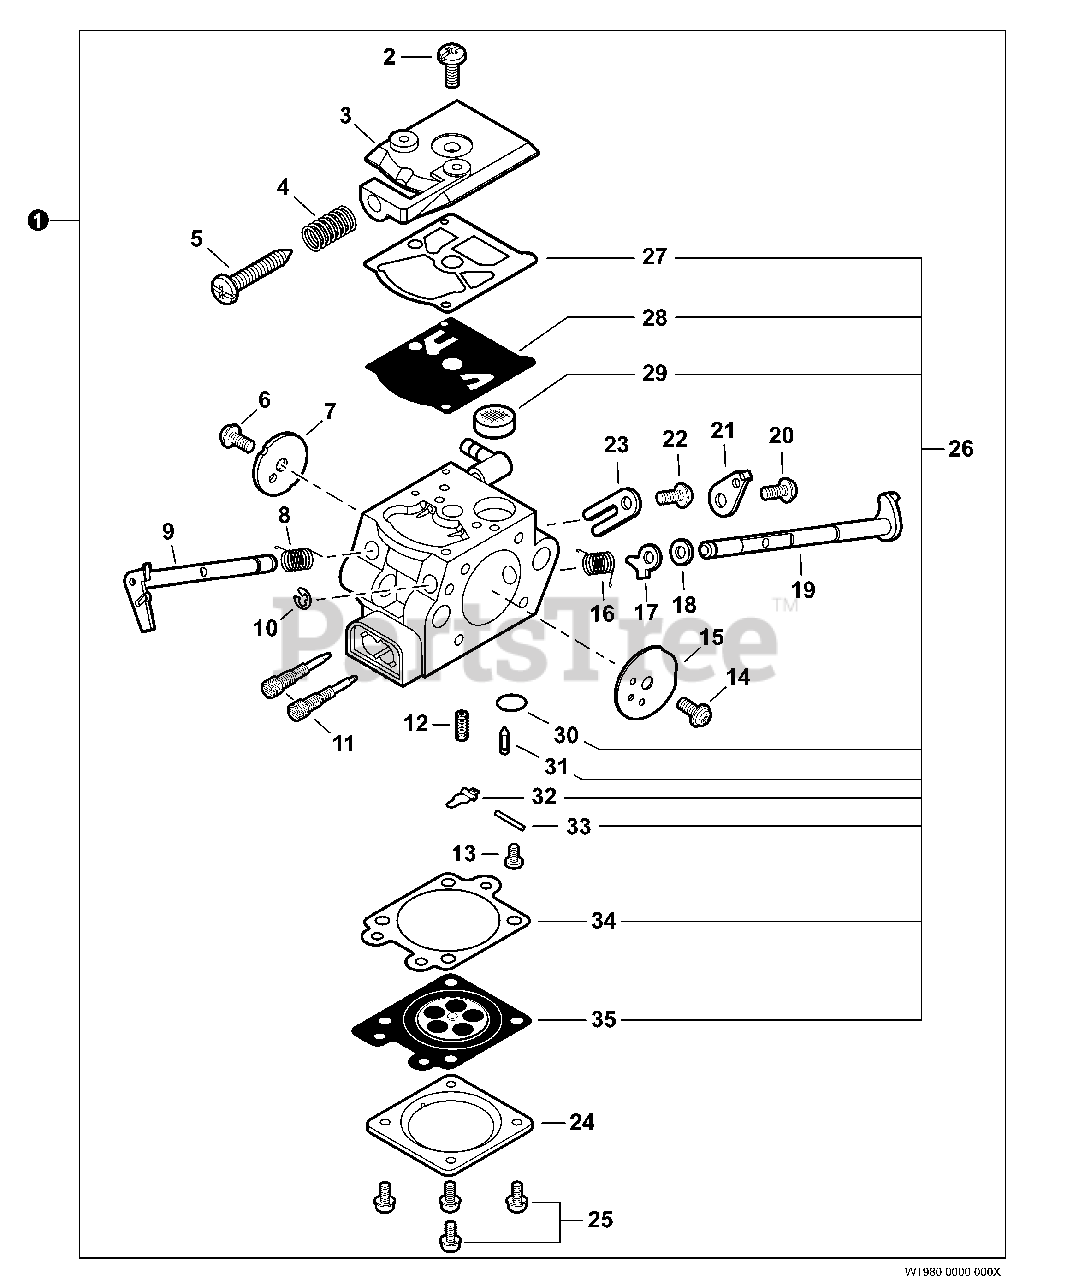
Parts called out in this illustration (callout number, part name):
1	CARBURETOR - WT-980
3	COVER, FUEL PUMP
4	SPRING, IDLE ADJUST
5	SCREW, IDLE ADJUST
7	VALVE, THROTTLE
8	SPRING, THROTTLE RETURN
9	SHAFT ASSY, THROTTLE
11	NEEDLE, MIXTURE
12	SPRING, METERING LEVER
13	SCREW, METERING LEVER PIN
15	VALVE, CHOKE
17	LEVER, FAST IDLE
19	SHAFT, CHOKE
21	LEVER, THROTTLE
23	CLIP, THROTTLE SHAFT
24	COVER, METERING DIAPHRAGM
26	REPAIR KIT
27	GASKET, PUMP
28	DIAPHRAGM, PUMP
29	SCREEN, INLET
30	PLUG, WELCH
31	VALVE, INLET NEEDLE
32	LEVER, METERING
33	PIN, METERING LEVER
34	GASKET, METERING DIAPHRAGM
35	DIAPHRAGM, METERING
